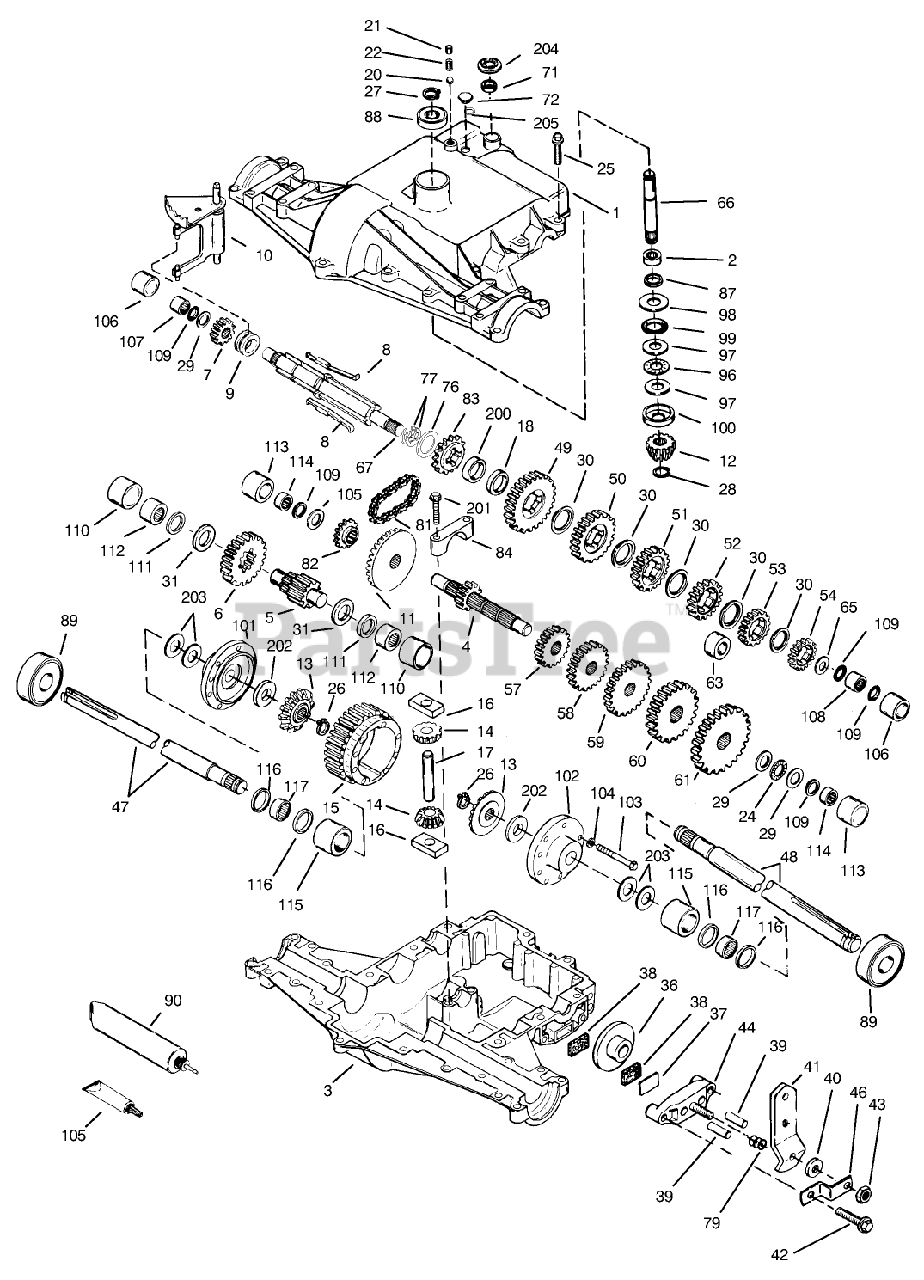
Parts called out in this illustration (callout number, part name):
1	Cover-Transaxle (Only On: 72042, 72062)
2	Bearing-Needle (Only On: 72042, 72062)
3	Case-Transaxle (Only On: 72042,72062)
4	Countershaft-Gear 9t (Only On: 72042, 72062)
5	Shaft-Output (Only On: 72042, 72062)
6	Gear-Output 35t (Only On: 72042,72062)
7	Gear-Spur 15t (Only On: 72042,72062)
8	Key-Shift (Only On: 72042, 72062)
8	Key-Shift (820-024A Only)
9	Collar-Shift
9	Shift Collar
10	Fork-Shift (Only On: 72042,72062)
10	Fork-Shift (820-024A Only)
11	Gear-Bevel 33t (Only On: 72042, 72062)
12	Pinion-Input Bevel 13t (Only On: 72042, 72062)
13	Gear-Bevel
14	Pinion-Bevel
15	Gear-Ring (Only On: 72042,72062)
16	Biock-Drive
17	Pin-Drive
18	Spacer .350-.340 Thick (Only On: 72042, 72062)
20	Ball-Steel
21	Screw-Set
22	Spring
24	Bearing-Thrust
25	Screw 5/16-18x1 1/4
26	Ring-Snap
27	Ring-Snap
28	Ring-Retainer
29	Washer
30	Washer
31	Washer (Only On: 72042,72062)
36	Washer (Only On: 72042, 72062)
37	Brake Pad Plate
38	Pad-Brake 2/Pkg
39	Dowel Pin
40	Washer
41	Lever-Brake
42	Ring Set (.020 O S)
43	Locknut
44	Nozzle-Carburetor
46	Bracket
47	Axle 12 9/16" Long (Only On: 72042,72062)
48	Axle 16 7/16" Long (Only On: 72042, 72062)
49	Gear-Spur 41t (Only On: 72042,72062)
50	Gear-Spur 35t (Only On: 72042,72062)
51	Gear-Spur 30t (Only On: 72042, 72062)
52	Gear Spur 25t (Only On: 72042,72062)
53	Gear Spur 22t (Only On: 72042,72062)
54	Gear Spur 19t
57	Gear Spur 15t (Only On: 72042, 72062)
58	Gear Spur 20t (Only On: 72042, 72062)
59	Gear Spur 25t (Only On: 72042, 72062)
60	Gear Spur 28t (Only On: 72042,72062)
61	Gear Spur 30t (Only On: 72042,72062)
65	Washer
66	Shaft-Input 30.910" Lg (Only On: 72042, 72062)
67	Shaft-Shifter/Brake (Only On: 72042, 72062)
67	Shaft-Shifter/Brake (820-024A Only)
71	Cut Seal-Square
72	Plug-Threaded 5/16-18
76	Washer
77	Inverted Retaining Ring
79	Piston ASM (.020 O S)
81	Chain-Roller
82	Sprocket 10t
83	Sprocket (14 teeth)
84	Cap-Bearing (Only On: 72042, 72062)
87	Seal Oil
88	Bearing-Ball
89	Bearing-Ball
90	Grease 32 Oz
96	Bearing-Thrust (Only On: 72042,72062)
97	Washer
98	Washer (Only On: 72042, 72062)
99	O Ring (Only On: 72042,72062)
100	Washer-Cupped (Only On: 72042,72062)
101	Carrier-Differential (Only On: 72042, 72062)
102	Carrier-Differential (Only On: 72042, 72062)
103	Screw-Hex Hd.
104	Lockwasher
105	Washer (Only On: 72042,72062)
106	Sleeve (Only On: 72042,72062)
107	Bearing-Needle (Only On: 72042,72062)
108	Bearing-Needle (Only On: 72042, 72062)
109	O Ring
110	Sleeve (Only On: 72042, 72062)
111	Ring-Square Cut (Only On: 72042, 72062)
112	Bearing-Needle (Only On: 72042, 72062)
113	Sleeve (Only On: 72042, 72062)
114	Bearing-Needle (Only On: 72042,72062)
115	Sleeve (Only On: 72042,72062)
116	Ring-Square Cut (Only On: 72042,72062)
117	Bearing-Needle (Only On: 72042,72062)
150	Gasket Eliminator
200	Spacer .276-.268 Thick (Only On: 72042, 72062)
201	Ring Set (.020 O S)
202	Washer
203	Washer
204	Pushnut
205	O Ring
